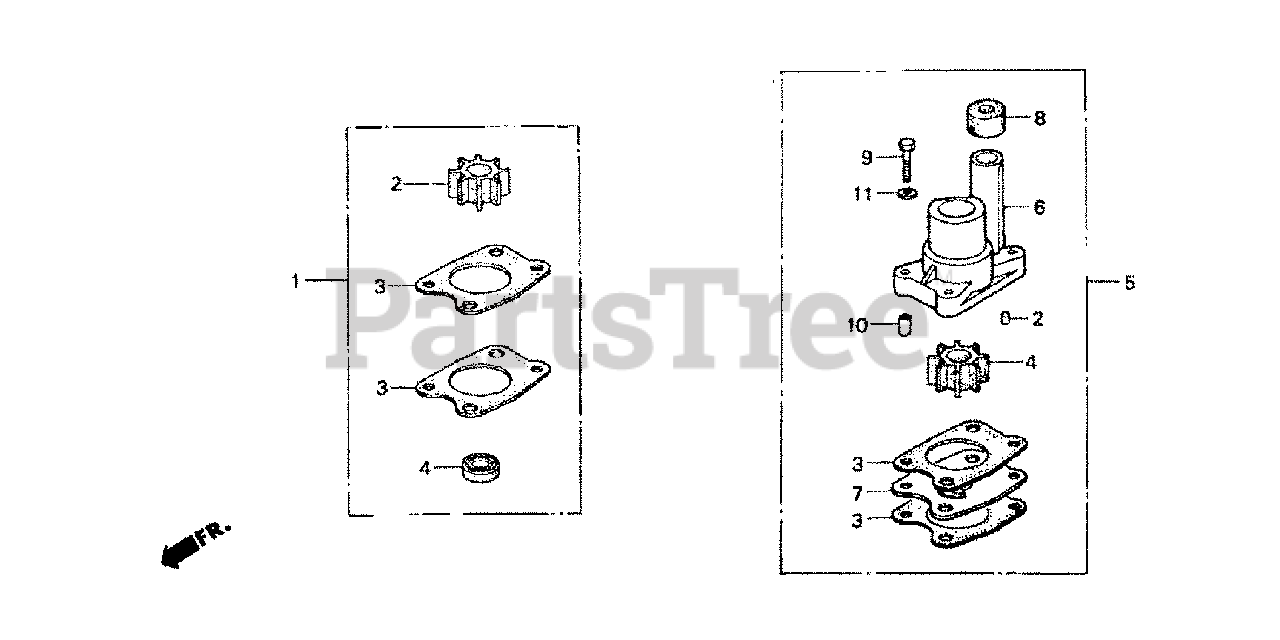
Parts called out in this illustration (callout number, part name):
1	IMPELLER KIT, WATER PUMP
2	IMPELLER, PUMP
3	GASKET, IMPELLER
4	SEAL, WATER (13MM) (ARAI)
